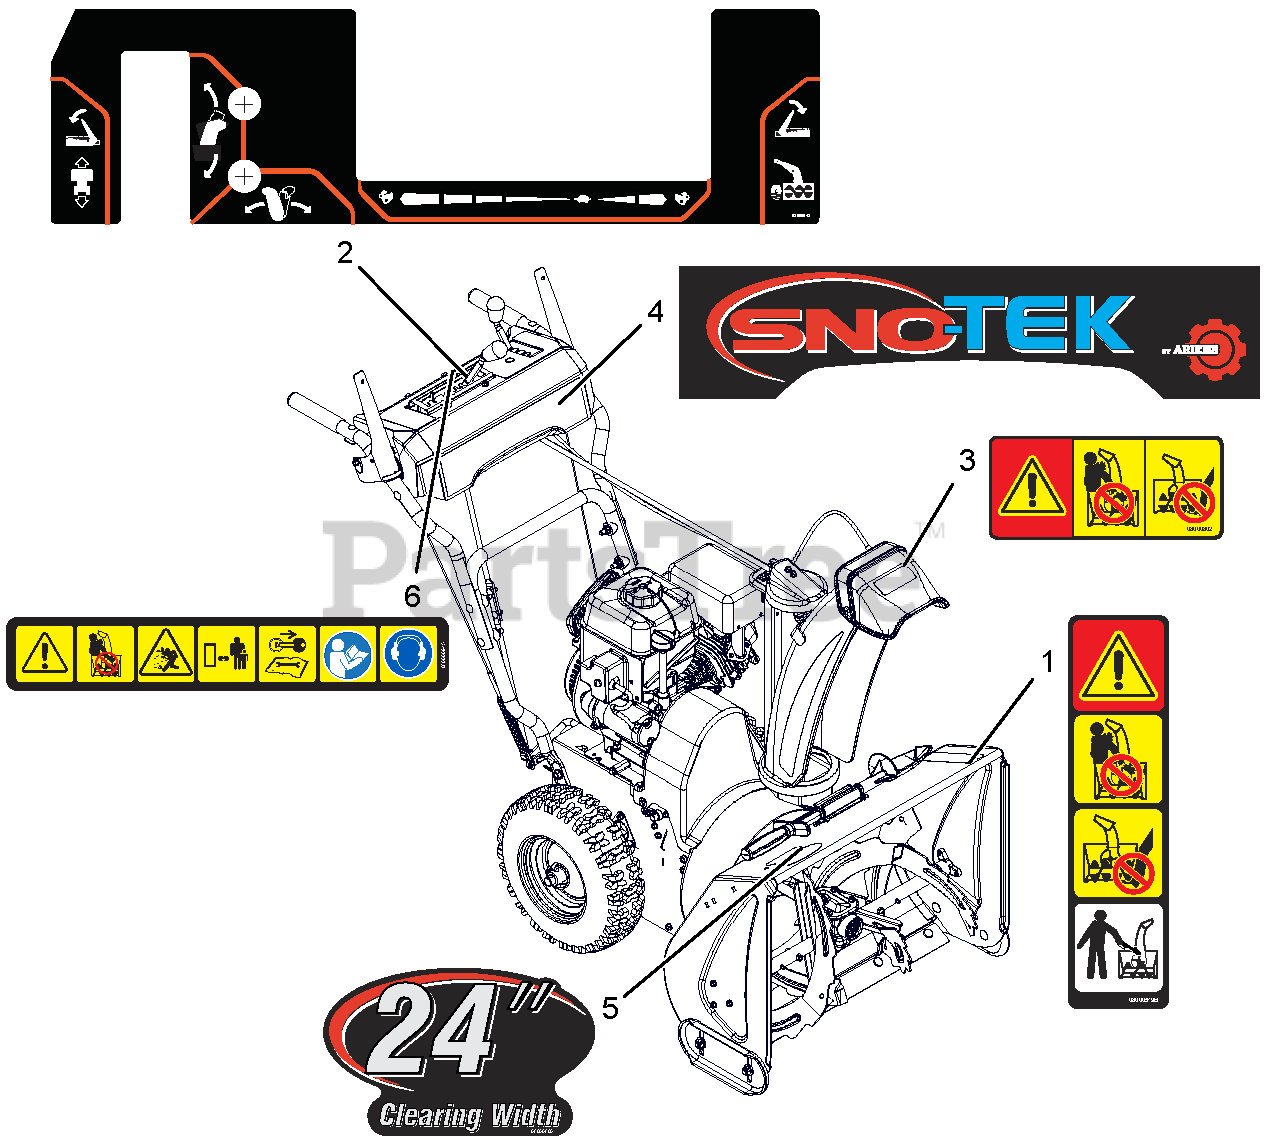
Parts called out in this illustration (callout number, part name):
1	DECAL, DANGER - ROTATING PARTS
2	DECAL,CONTROL-COMP REMOTE
3	DECAL, DANGER SNO-TEK
4	DECAL, DASH - SNO-TEK
5	DECAL, HOUSING SNO-TEK 24
6	DECAL,DASH - SAFETY
